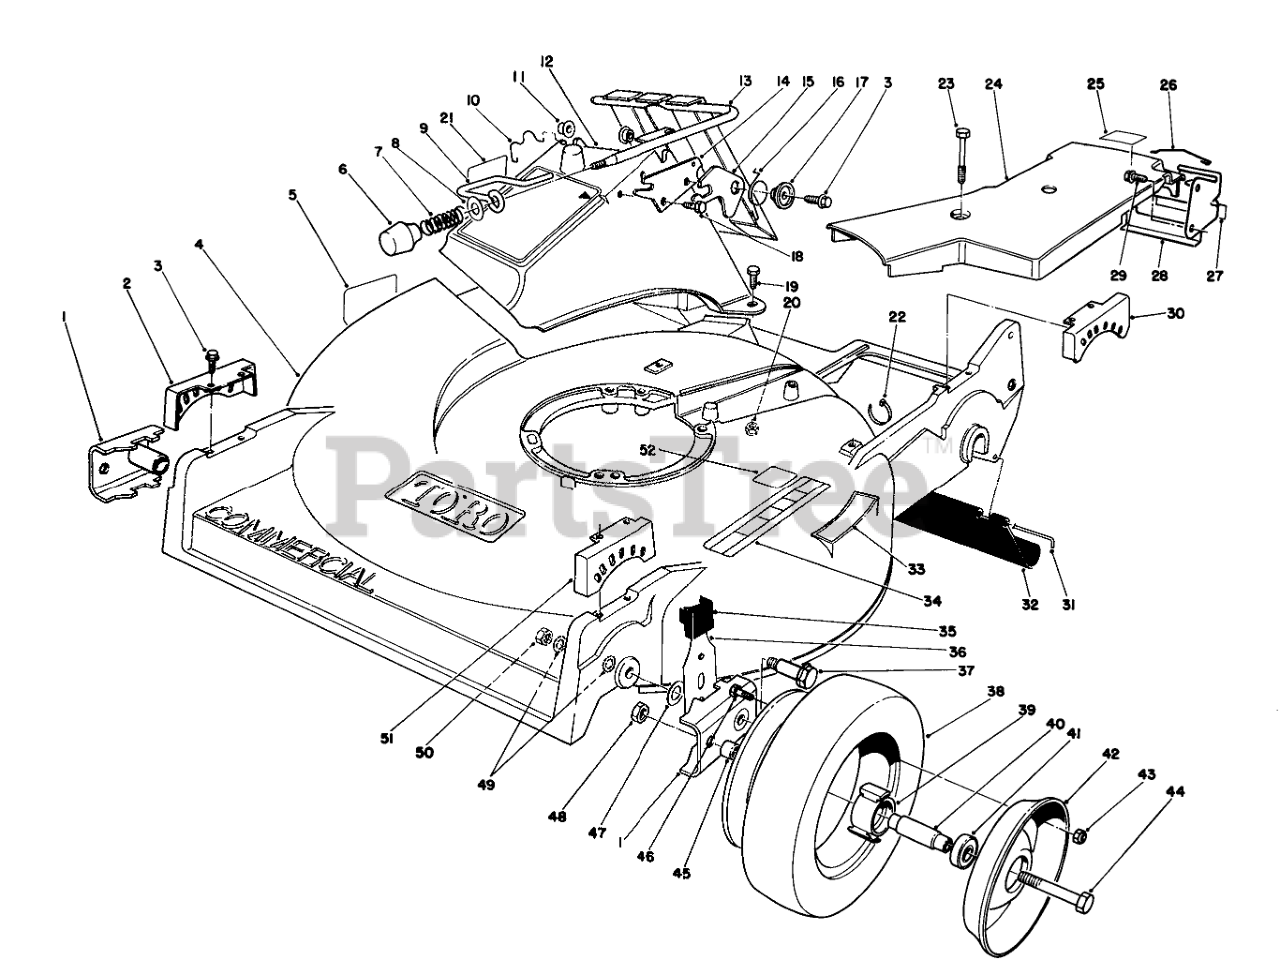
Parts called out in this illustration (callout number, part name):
1	ARM-PIVOT, FRONT
2	QUADRANT-FRONT, RH
3	SCREW-HWHTF
4	Housing-Commercial (Incl. Ref. #5, 33 & 34)
5	Decal Danger
7	COMPRESSION SPRING
8	WASHER-FLAT
9	DOOR LATCH
10	DOOR RETAINER
11	BUSHING-NYLON
12	DISCHARGE CHUTE B
13	DOOR & HANDLE WA
14	DOOR LATCH PLATE
15	SAFETY LATCH
16	TORSION SPRING
17	DOOR SPACER
18	SCREW-HWH
19	SCREW-HH
20	NUT-LOCK, NI
21	DECAL - DANGER
22	TIE-CABLE
23	SCREW-HHFTF
24	COVER-BELT
25	Label-Grease
26	RETAINER-CABLE
27	DECAL-POSITION, GEAR
28	BRKT-TRACTION ADJ.
29	SCREW-HWHTF
30	QUADRANT-REAR, LH
31	ROD-SHIELD
32	SHIELD-TRAILING
33	DECAL - STEP PAD INT'L
34	Decal-Safety Instructions
35	KNOB-ARM
36	FRONT SPRING ARM ASM
37	WHEEL BOLT
39	HUB-BEARING
40	SPACER-BEARING
41	BEARING-WHEEL
42	Wheel-Half
43	NUT-LOCK, NI
44	SCREW-HH
45	SPACER-WHEEL
46	SCREW-HH
47	WASHER-THRUST
48	NUT-LOCK, CONE
49	WASHER
50	Nut
51	QUADRANT-FRONT, LH
52	Decal-Noise
